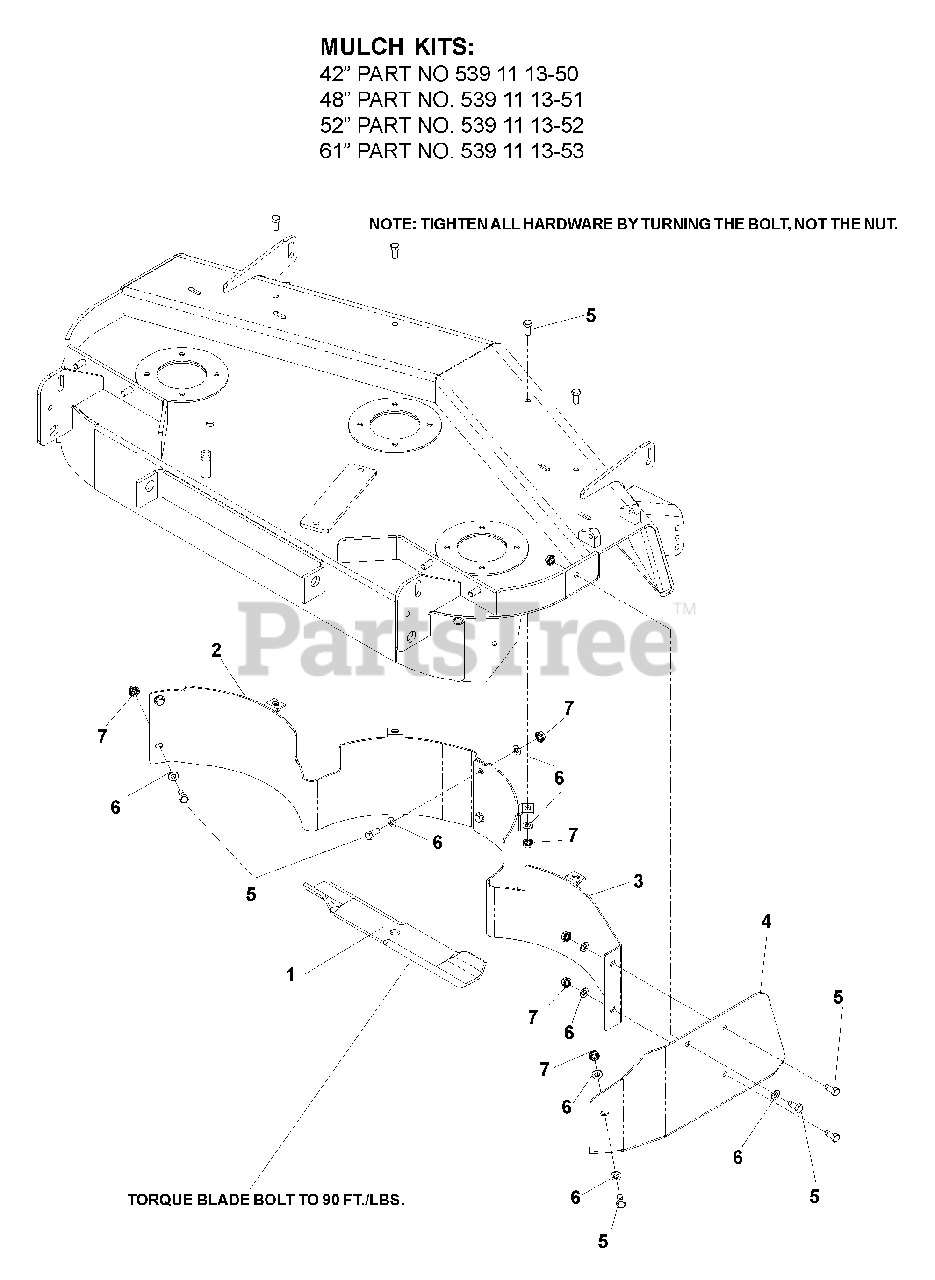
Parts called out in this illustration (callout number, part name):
1	MULCH BLADE, 42 DECK, 14 7/8
1	MULCH BLADE, 48 DECK, 16 1/4
1	MULCH BLADE, 52 DECK, 18
1	MULCH BLADE, 61 DECK, 21
2	MULCH BAFFLE, LEFT, 42 DECK
2	MULCH BAFFLE, LEFT, 48 DECK
2	MULCH BAFFLE, LEFT, 52 DECK
2	MULCH BAFFLE, LEFT, 61 DECK
3	MULCH BAFFLE, RIGHT, 42 DECK
3	MULCH BAFFLE, RIGHT, 48 DECK
3	MULCH BAFFLE, RIGHT, 52 DECK
3	MULCH BAFFLE, RIGHT, 61 DECK
4	MULCH CAP, 42 DECK
4	MULCH CAP, 48 DECK
4	MULCH CAP, 52 DECK
4	MULCH CAP, 61 DECK
5	HCS, 5/16-18 X 3/4, GR5
6	WASHER, 5/16, SAE
7	NUT, 5/16-18, WHIZLK
539111350	MULCH KITS 42"
539111351	MULCH KITS 48"
539111352	MULCH KITS 52"
539111353	MULCH KITS 61"
